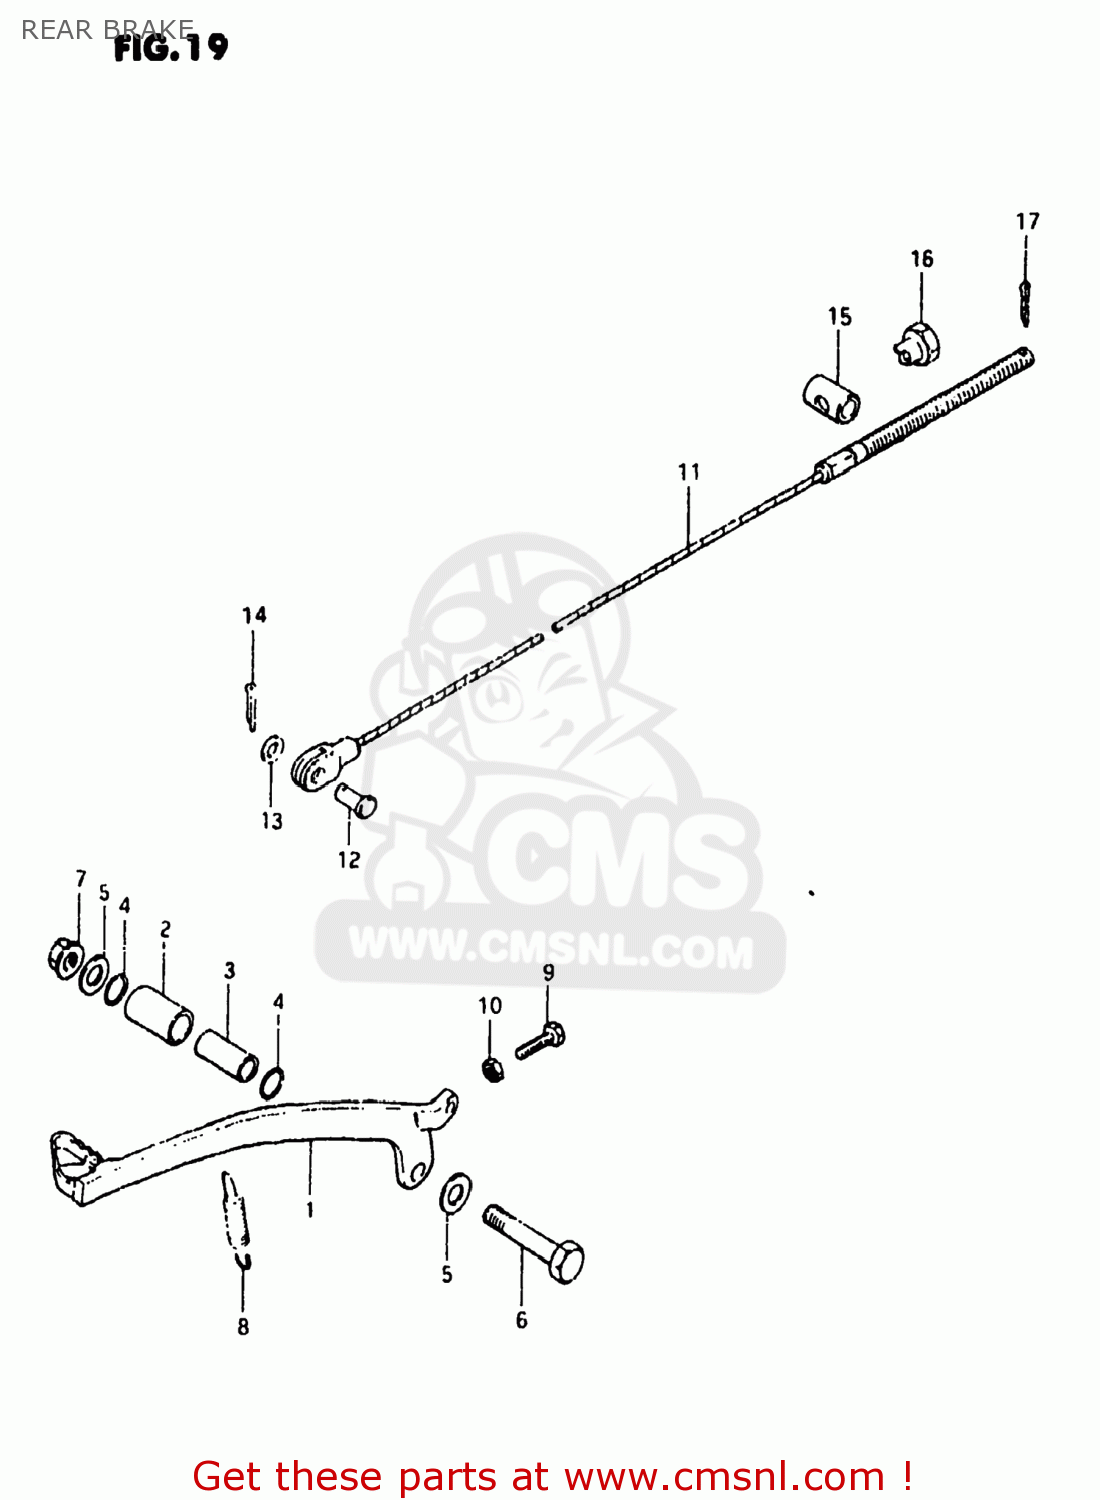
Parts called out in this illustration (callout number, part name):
1	PEDAL,BRAKE
2	BUSH
3	SPACER(10X14X32.2)
4	O RING(D:1.5,ID:13.8)
5	WASHER
6	BOLT
7	NUT
8	SPRING
9	BOLT(6X23)
10	NUT
11	CABLE,RR BRAKE
12	PIN(L:17.5)
13	WASHER
14	PIN 20X20
15	PIN
16	NUT
17	PIN
